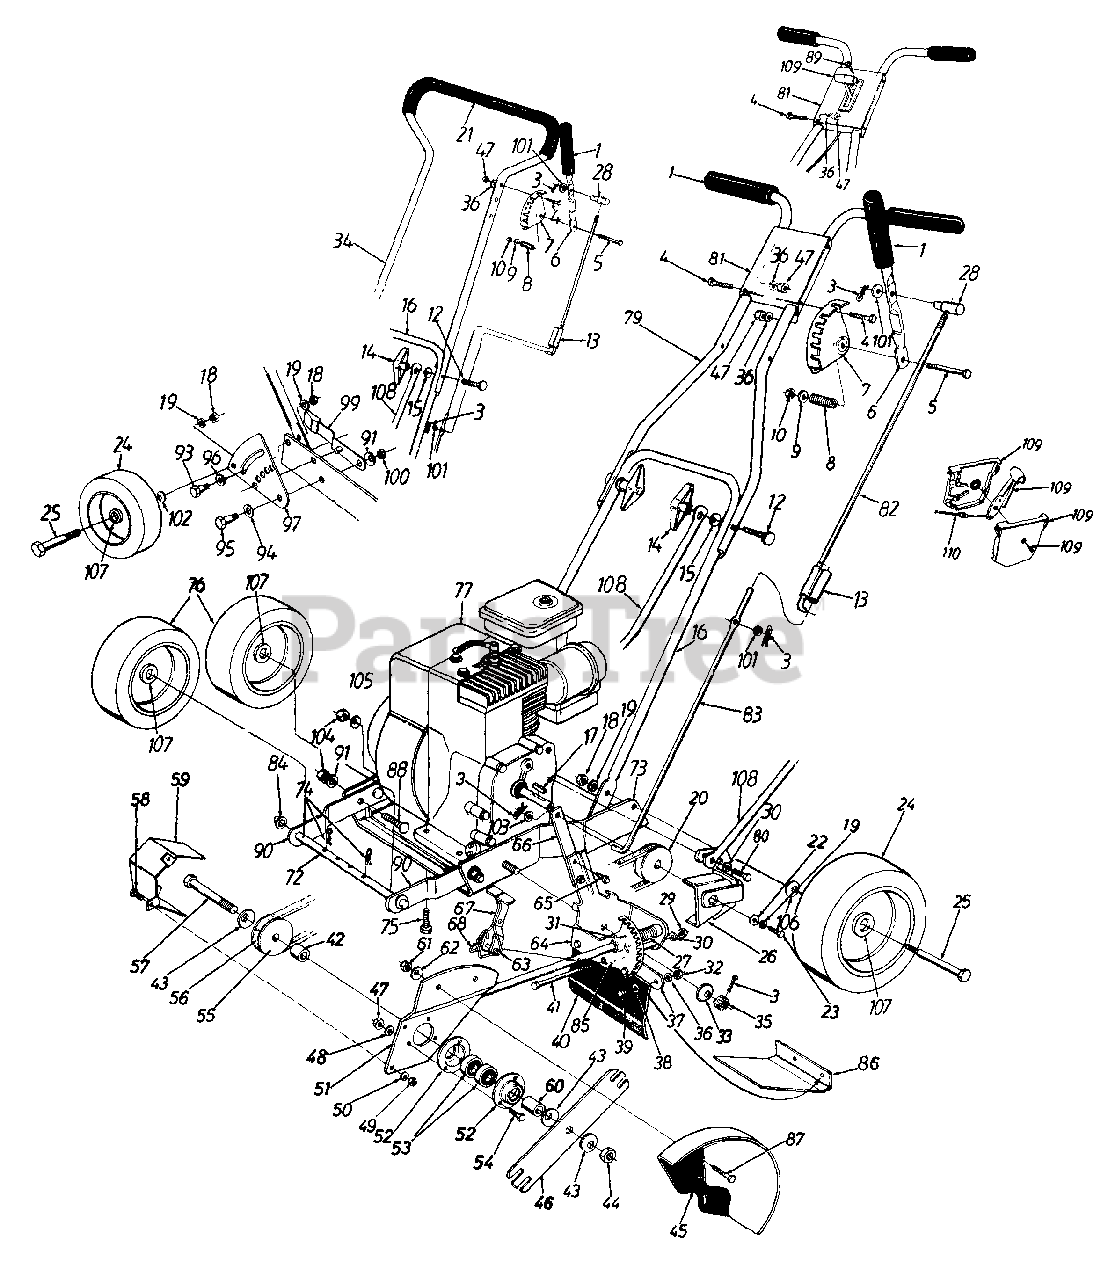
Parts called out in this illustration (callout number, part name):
1	Foam Grip
3	Cotter Pin 5/16" Dia.
4	Hex Bolt 1/4-20 x 1.25" Lg.
5	Hex Bolt 5/16-18 x 2" Lg.
8	Compression Spring 1.38" Lg.
9	Fl-Wash..344" I.D.
10	Hex L-Nut 5/16-18 Thd.
12	Curv. Hd. Bolt 5/16-18 x 2" Lg.
13	Clutch Rod Lock
14	Wing Nut Ass'y.
15	Saddle Wash. .32" I.D. x .937"
18	Hex Nut 3/8-16 Thd.
19	L-Wash. 3/8" I.D.
20	Engine Pulley
21	Foam Grip
22	Fl-Wash..385" I.D.
23	Hex Bolt 3/8-24 x 1" Lg.
24	Rear Wheel Ass'y.- Bar Tread
25	Shoulder Bolt .498" Dia.
28	Ferrule
29	Hex Nut 5/16-18 Thd.
30	I-Wash. 5/16" I.D.
31	Spring Pin Spir. 1/4" Dia.
32	Hex Nut 1/4-20 Thd.
33	Bell-Wash. .535" I.D.
34	Upper Loop Handle
35	Hex Slotted Nut 1/2-20 Thd.
36	L-Wash. 1/4" I.D.
39	Hex Bolt 1/4-20 x .62" Lg.
41	Hex Bolt 5/16-18 x 4.5" Lg.
42	Spacer 1.030" Lg.
43	Bell-Washer. .63" I.D.
44	Hex Jam L-Nut 5/8-18 Thd.
47	Hex Nut 1/4-20 Thd.
48	L-Wash. 1/4" I.D.
49	Hex Nut 1/4-20 Thd.
50	L-Wash. 1/4" I.D.
53	Ball Bearing .62" I.D.
54	Hex Bolt 1/4-20 x .62" Lg.
55	3/8" "V"-Pulley
56	"V"-Belt
57	Hex Bolt 5/8-18 x 4.5" Lg.
58	Hex Bolt 1/4-20 x .625" Lg.
60	Sleeve .90" Lg.
61	Hex Nut 5/16-18 Thd.
62	Bell-Wash. .345" I.D.
63	Spring Pin Spir. 1/4" Dia.
68	Torsion Spring
72	Axle 8.20" Lg. (Front)
75	Hex L-Wash. TT-Tap Scr. 3/8-16 x 1" Lg.
76	Front Wheel Ass'y.- Bar Tread
77	Engine
83	Lower Clutch Rod
84	Push Cap 1/2" Dia.
85	Spacer 3.765" Lg.
88	Ribbed Neck Bolt 3/8-24 x .8" Lg.
89	Self-Tap Scr. #10 x .5" Lg.
93	Shld. Bolt .5" Dia.
94	Bell-Wash. .515" I.D.
95	Shld. Bolt .50" Dia.
96	Fl-Wash. .51" I.D. x .94"
100	Hex Jam Nut 3/8-16 Thd.
101	Fl-Wash. .344" I.D. x .62" O.D.
102	Wave Wash. .51" I.D.
103	Fl-Wash. .406" I.D. x .81" O.D.
104	Hex Nut 3/8-24 Thd.
105	Bell-Wash. .396" I.D. x 1.14" O.D.
106	Bell-Wash. .38" I.D. x .88" O.D.
107	Plastic Bearing
110	Throttle Wire 39" Lg.
